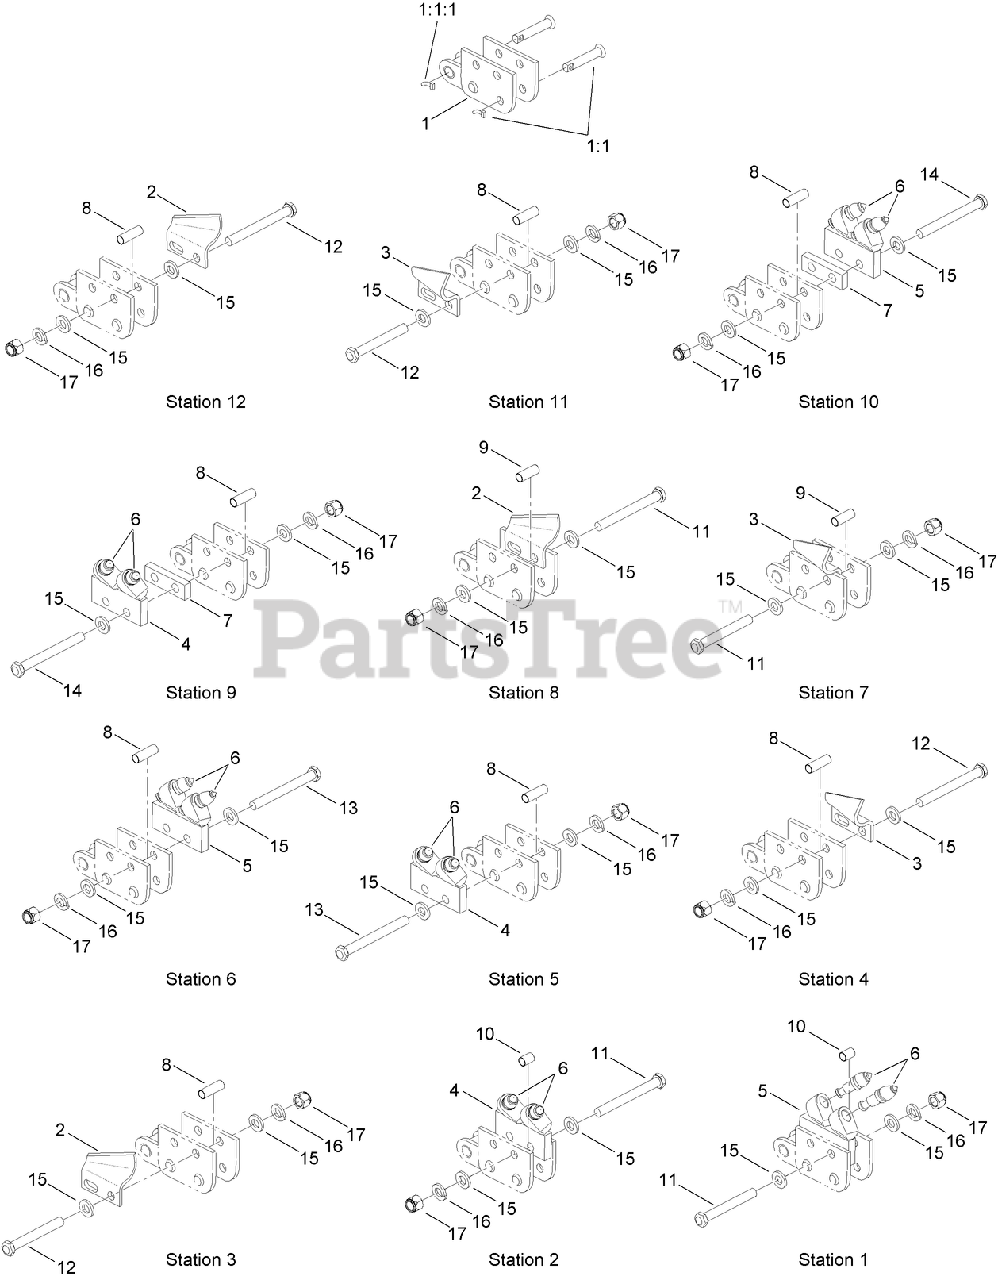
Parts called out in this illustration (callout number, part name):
1	CHAIN REPAIR LINK ASM
1:1	NOTCHED PIN AND KEEPER ASM
1:1:1	PIN-KEEPER
2	CUTTER-CUP, MIXED, LH
3	CUTTER-CUP, MIXED, RH
4	HOLDER-BIT, RH
5	HOLDER-BIT, LH
6	BIT-RETAINER, REAR
7	SPACER-FLAT
8	SPACER-TUBE, OUTSIDE MOUNT
9	SPACER-TUBE, INSIDE CUP MOUNT
10	SPACER-TUBE, INSIDE ADAPTER
11	BOLT-HH
12	BOLT-HH
13	BOLT-HH
14	BOLT-HH
15	WASHER-FLAT
16	WASHER-LOCK
17	NUT-LOCK
